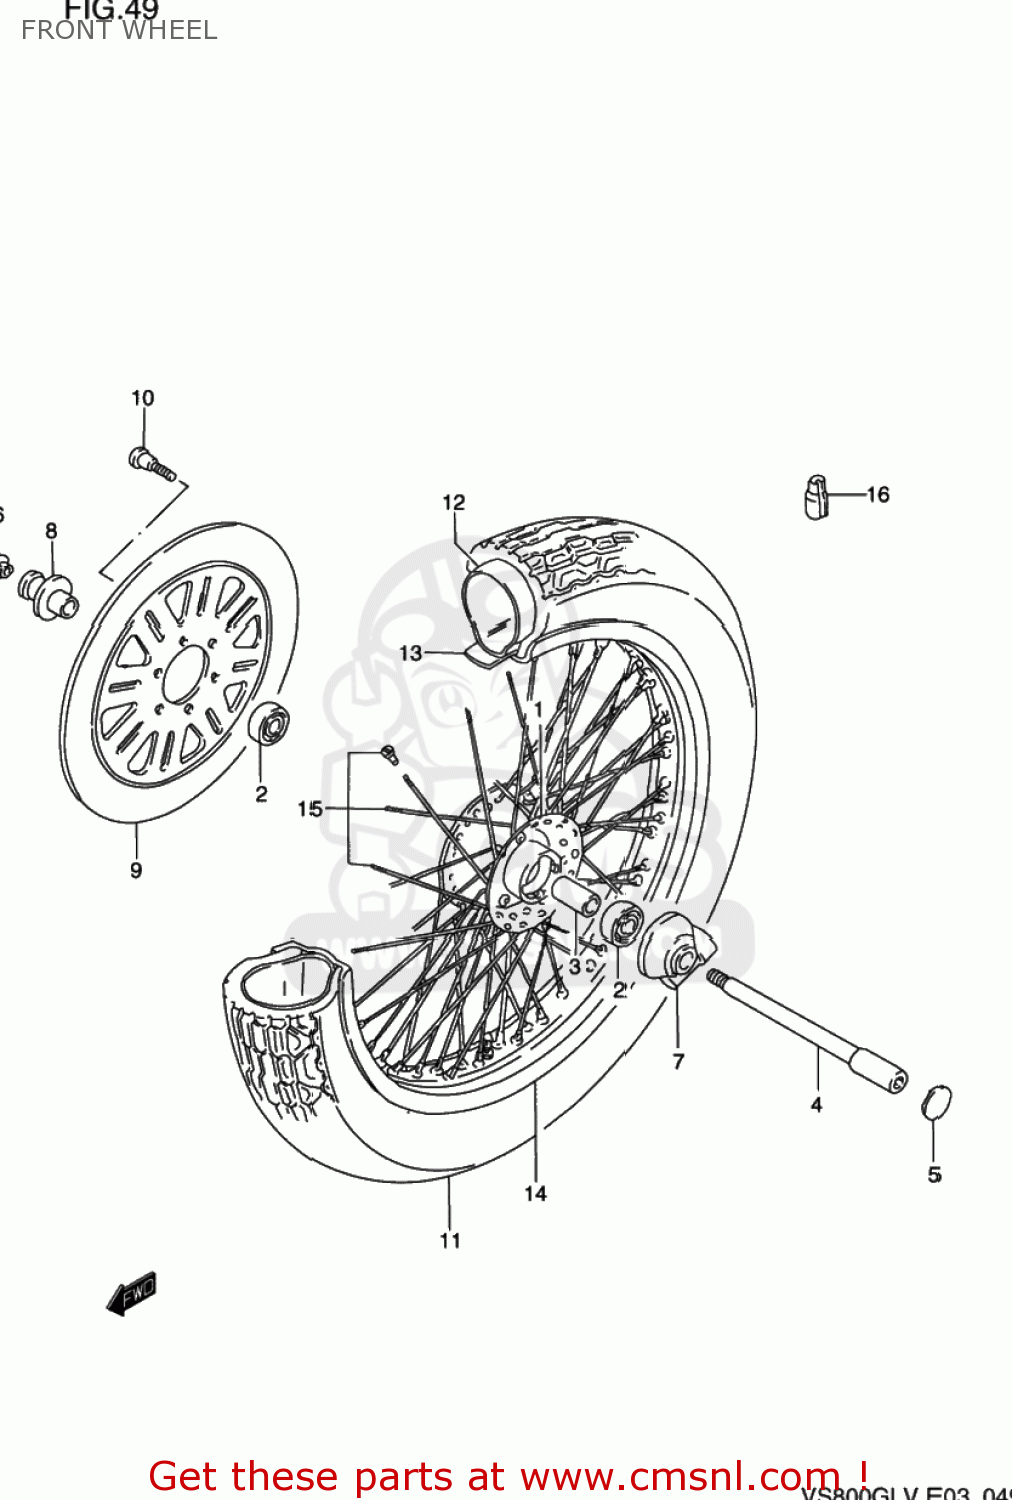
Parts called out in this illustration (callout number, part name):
1	HUB ASSY,FR
2	BEARING
3	SPACER(15.3X21.7X65)
4	AXLE,FR
5	CAP,FR AXLE
6	CAP,FR AXLE
7	BOX ASSY,SPEEDOMETER
8	SPACER,FR AXLE
9	DISC,FR BRAKE
10	BOLT 8X33
11	TIRE,FR(80/90 21 48H)
12	TUBE
13	PROTECTOR,WHEEL INNER
14	RIM,FR WHEEL(21X2.15 AL)
15	SPOKE SET,FR WHEEL
16	BALANCER,WHEEL
